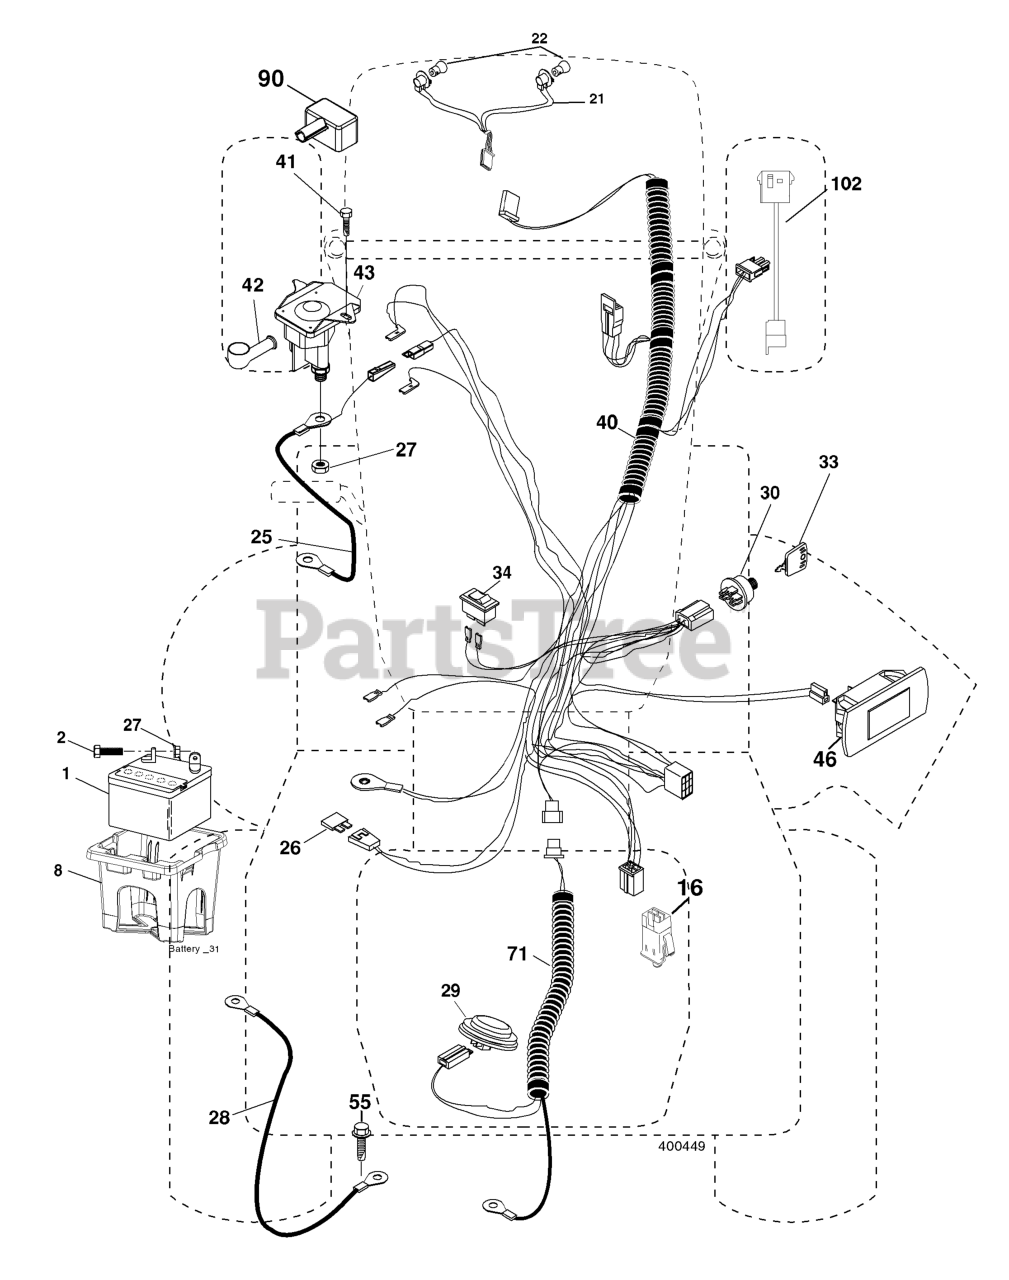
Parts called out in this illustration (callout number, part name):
1	Battery
2	BOLT.HEX.1/4.X.3/4.DICHROMATE
8	BOX.BATTERY.MNT.REAR.L
16	SWITCH INTERLOOK PUSH-IN
21	HARNESS ASSY LIGHT
25	CABLE.START.RED.17.5".
26	FUSE 20AMP
27	NUT
28	CABLE.BLACK.18"REAR.BA
29	SWITCH.SEAT.DELTA.OPC.
30	SWITCH.IGN.DELTA.W.LGH.ROS
33	KEY MLD GEN DELTA
40	HARNESS.IGN.CHASS.TEX.REAR.BAT
41	SCREW
42	TERMINAL COVER
43	SOLENOID.W/BRASS.PLUNGER
46	RP.GUAGE.SRVCMNDR.HRMTR.
50	RP.PTO.SWITCH.8 TERMINAL.BLACK
55	SCREW 5/16"
71	HARNESS IGN. DASH
90	COVER, TERMINAL BATTERY
102	HARNESS PIGTAIL PCH TEX ROS
